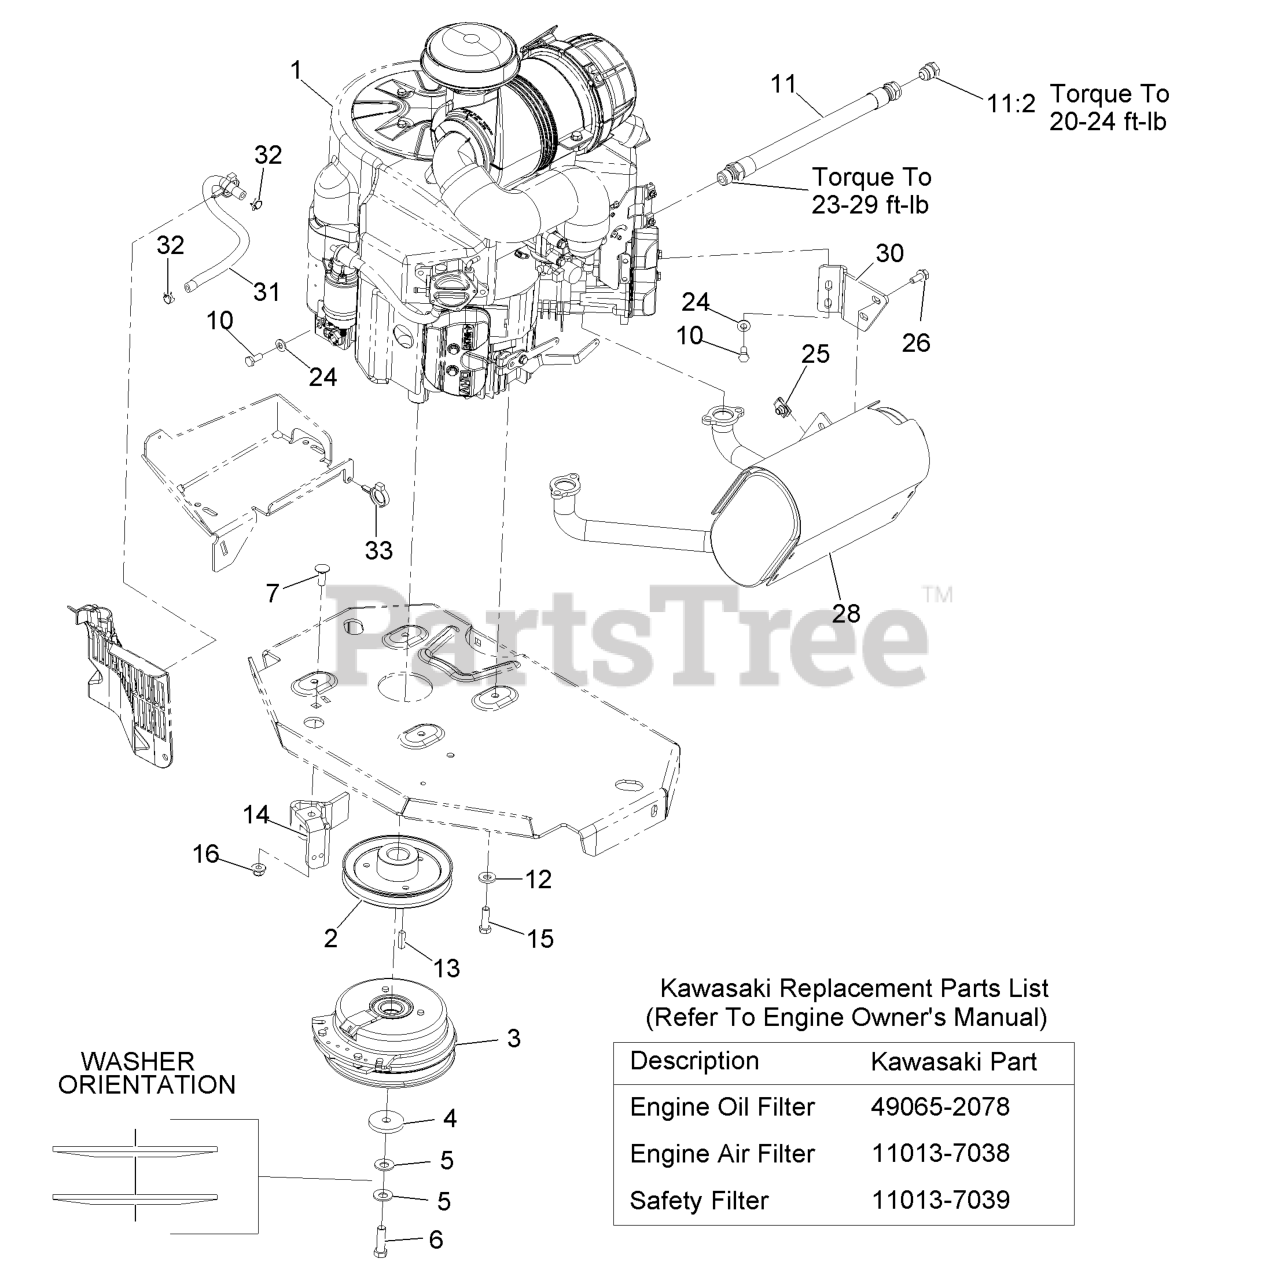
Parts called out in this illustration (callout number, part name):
2	SHEAVE
3	CLUTCH KIT
4	WASHER-CLUTCH
5	WASHER-SPRING
6	SCREW-HH 7/16-20 X 1 1/2 W/LOCTITE
7	SCREW-CARR
10	SCREW-HH
12	WASHER-BELLEVILLE
14	CLUTCH-ANCHOR
15	SCREW-HH
16	NUT-HF, NI
24	WASHER-SPRING
26	SCREW-HHF
28	MUFFLER
30	BRACKET-MUFFLER
31	HOSE-FUEL
32	CLAMP-HOSE
33	CLAMP-HOSE
